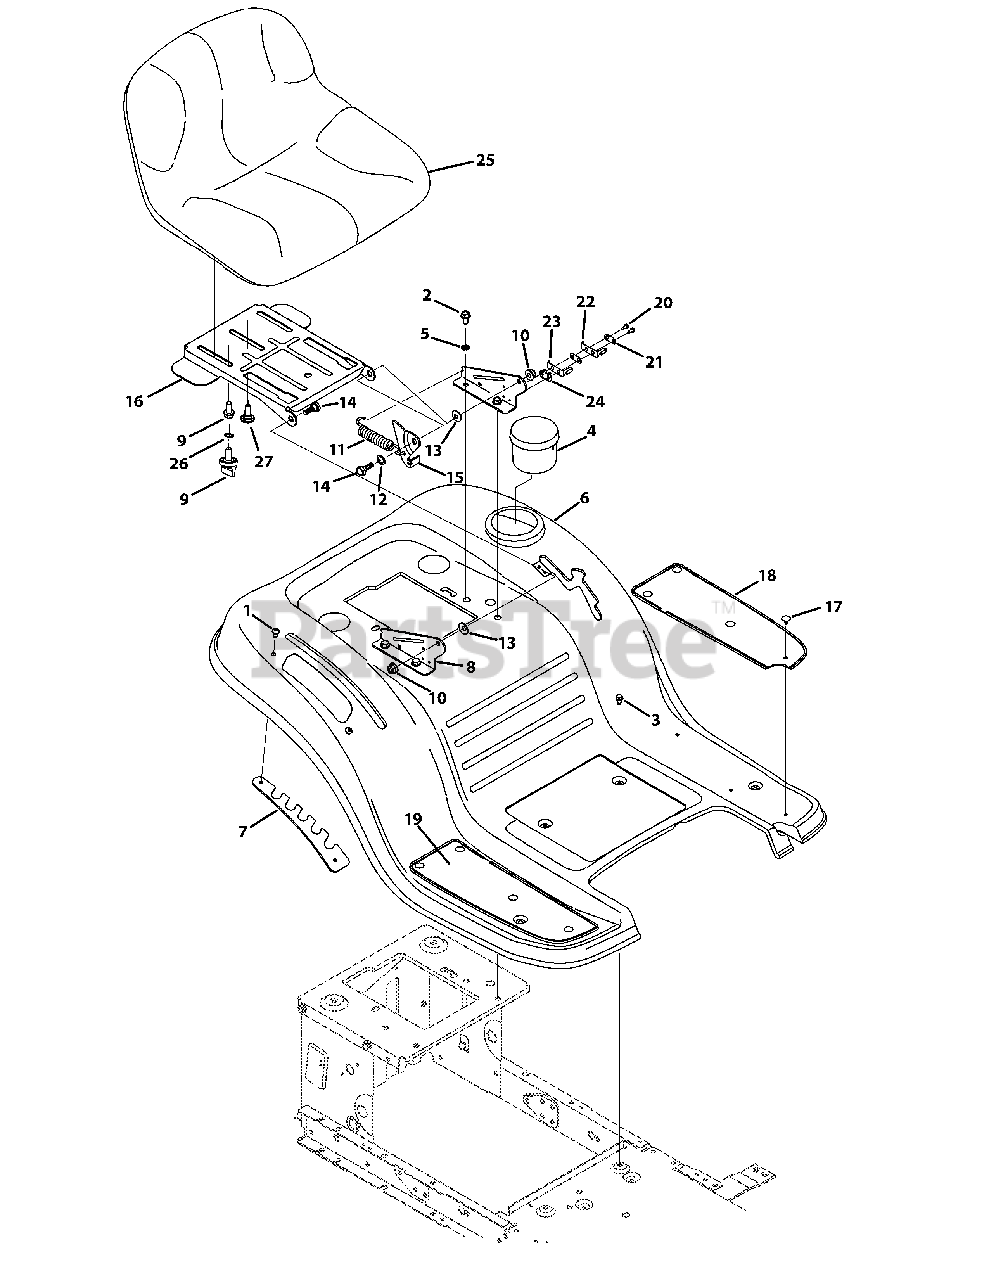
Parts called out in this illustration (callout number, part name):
1	Screw, 1/4-20 x .500
2	Screw, 5/16-18 x .750
3	Screw Pan Torx Head, 1/4-20 x .500
4	Cup Holder
5	Loack Washer, 5/16
6	Fender
7	Lift Adjuster Bracket
8	Seat Mount Bracket
9	Hex Flange, 3/8-16 x .875
9	Knob
10	Flangelock Nut, 5/16-18
11	Extension Spring
12	Flat Washer, .510x .750 x .033
13	Bell Washer, .340 x .872 x .060
14	Shoulder Screw, 5/16-18 x .437 x .268
15	Lift Seat Bracket
16	Pivot Seat Manual Adjust Bracket
17	Ratchet Clip, .250 x .500
18	Foot Pad, LH
18	Foot Pad, Abrasive, LH
19	Foot Pad, RH
19	Foot Pad, Abrasive, RH
20	Screw, 8-18 x .500
21	Insulator Plate
22	Outer Seat Spring
23	Inner Seat Spring
24	Insulator Boss Plate
25	Medium Back Seat, MTD Gold
25	High Back Seat
26	Lock Washer
27	Screw, Shldr., .625 x .145 x 3/8-16
